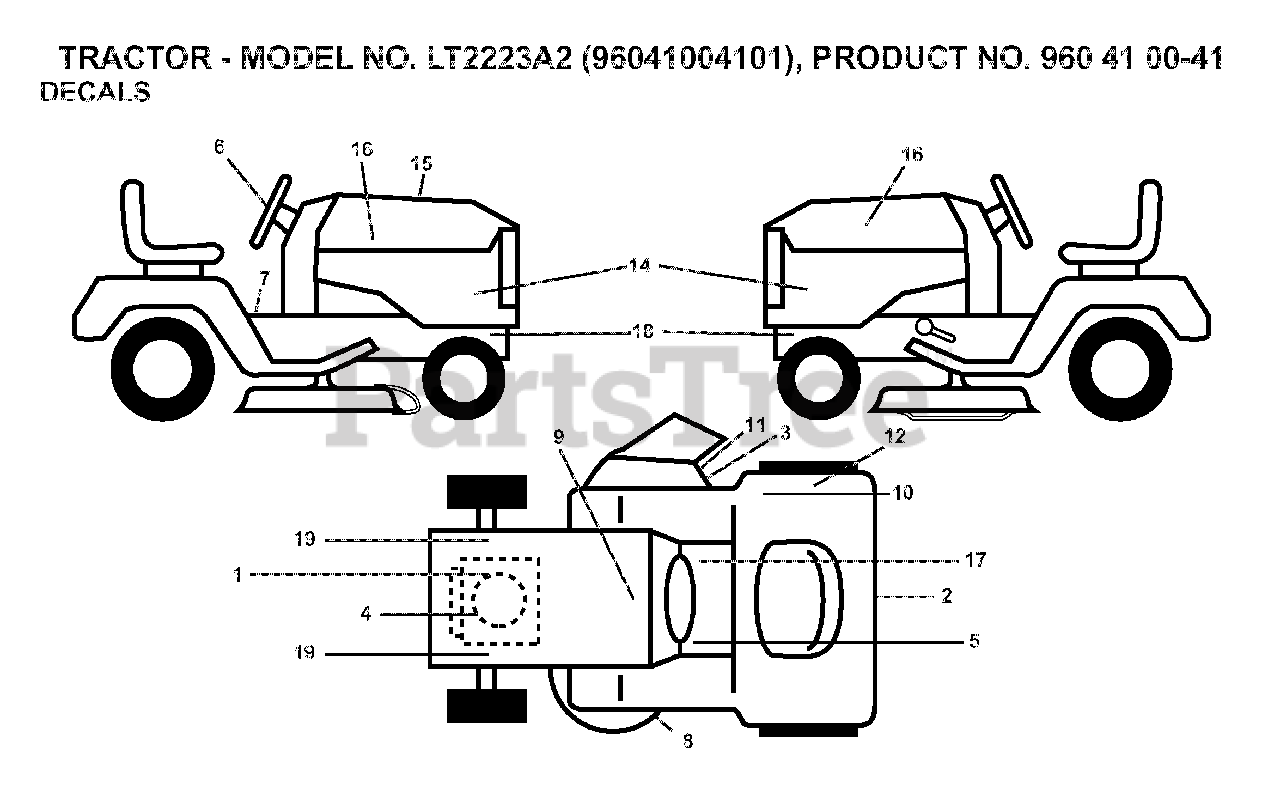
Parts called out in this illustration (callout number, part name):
1	DECAL.B&S.900.TANK.REF.276991
3	DECAL, DEFLECT WARNING
8	DECAL.MOWER.SCH.48/54
9	DECAL BTRY SYMBOLS
10	DECAL.FENDER
11	DECAL.INTERNATIONL.CUTFINGER
17	DECAL PARK BRAKE
